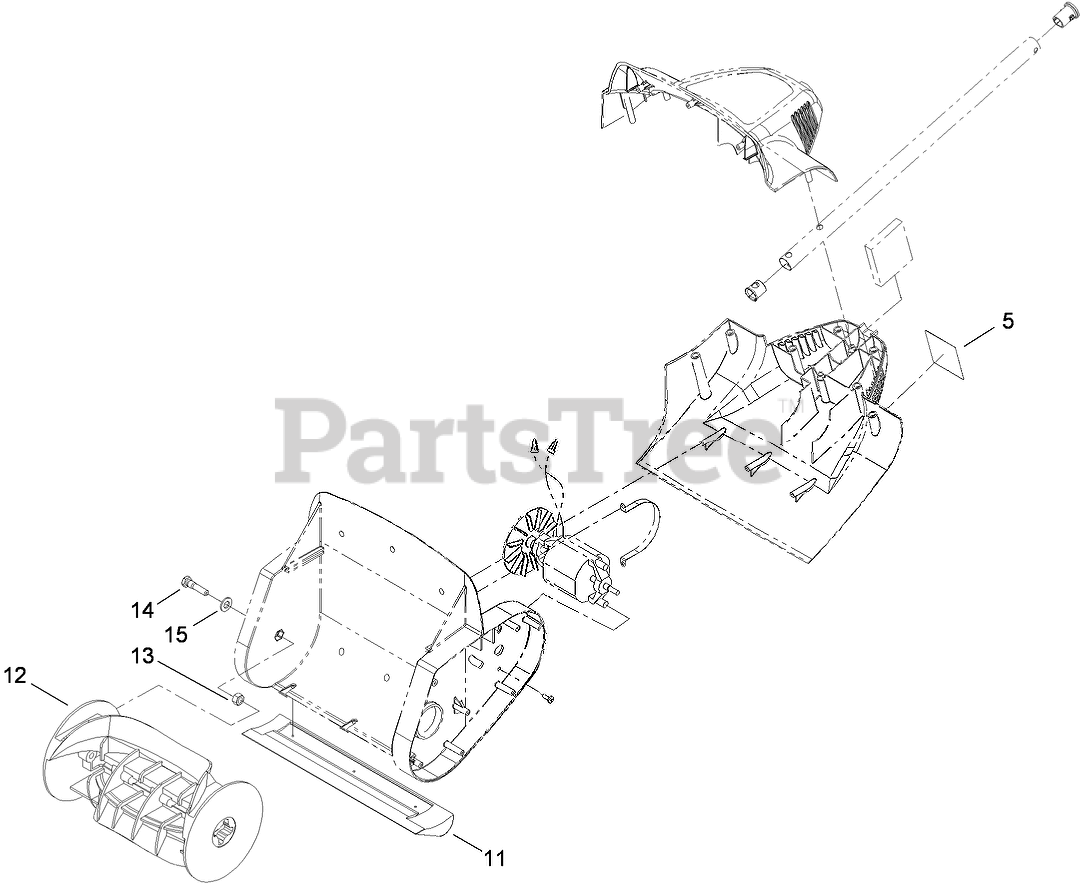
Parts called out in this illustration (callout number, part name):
5	DECAL-DANGER
11	SCRAPER-SNOW
12	ROTOR-SNOW
13	NUT-LOCK
14	PIN-ROTOR
15	WASHER-FLAT
